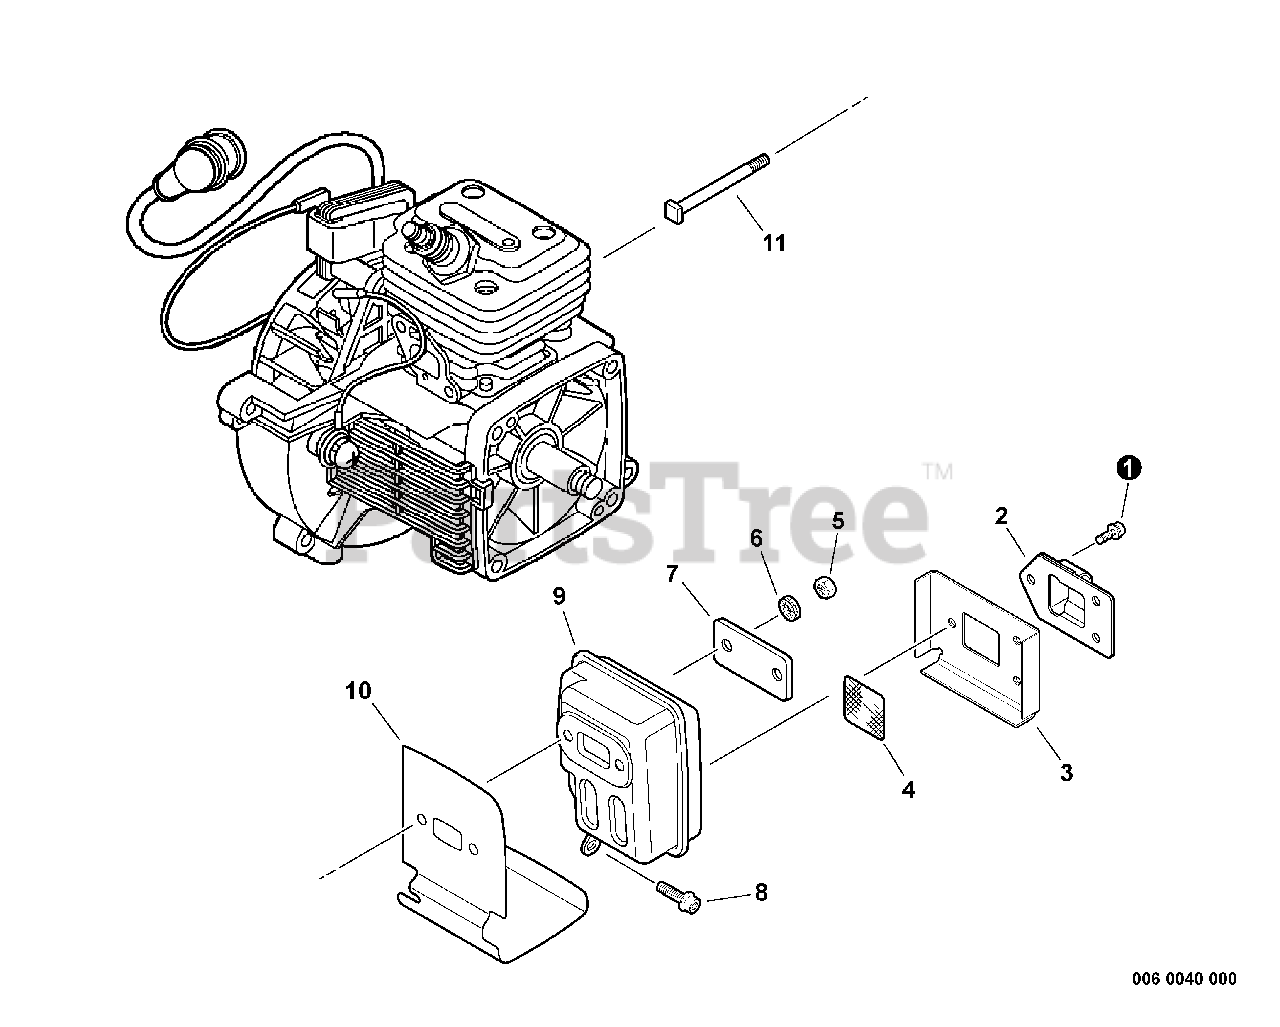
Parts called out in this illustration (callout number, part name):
1	SCREW - 4X12
2	GUIDE, EXHAUST
3	GASKET, EXHAUST
4	SCREEN, SPARK ARRESTOR
6	LOCKWASHER
8	SCREW - 5X16
9	MUFFLER
10	SHIELD, EXHAUST
